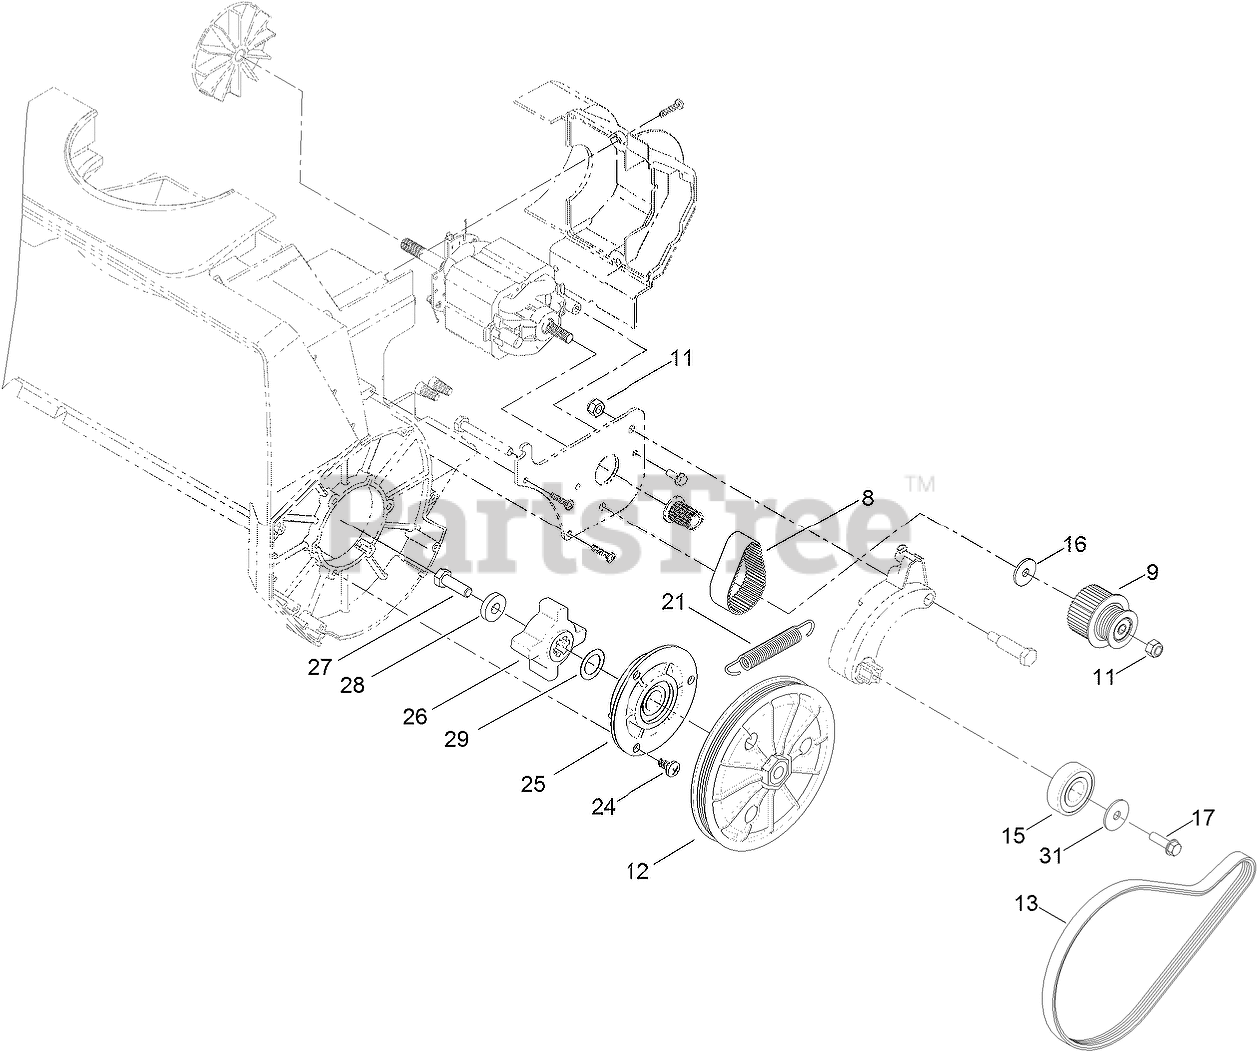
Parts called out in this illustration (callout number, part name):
8	BELT-PULLEY, IDLER/DRIVER
9	IDLER PULLEY ASM
11	NUT-LOCK, NI
12	PULLEY ASM
13	BELT-DRIVE
15	BEARING-BALL
16	WASHER-FLAT
17	SCREW-HWH
21	SPRING-IDLER
24	SCREW-SEAT, SWITCH
25	PILLOW BLOCK ASM
26	COUPLER-PULLEY
27	SCREW-HH
28	SPACER
29	WASHER
31	WASHER-FLAT
